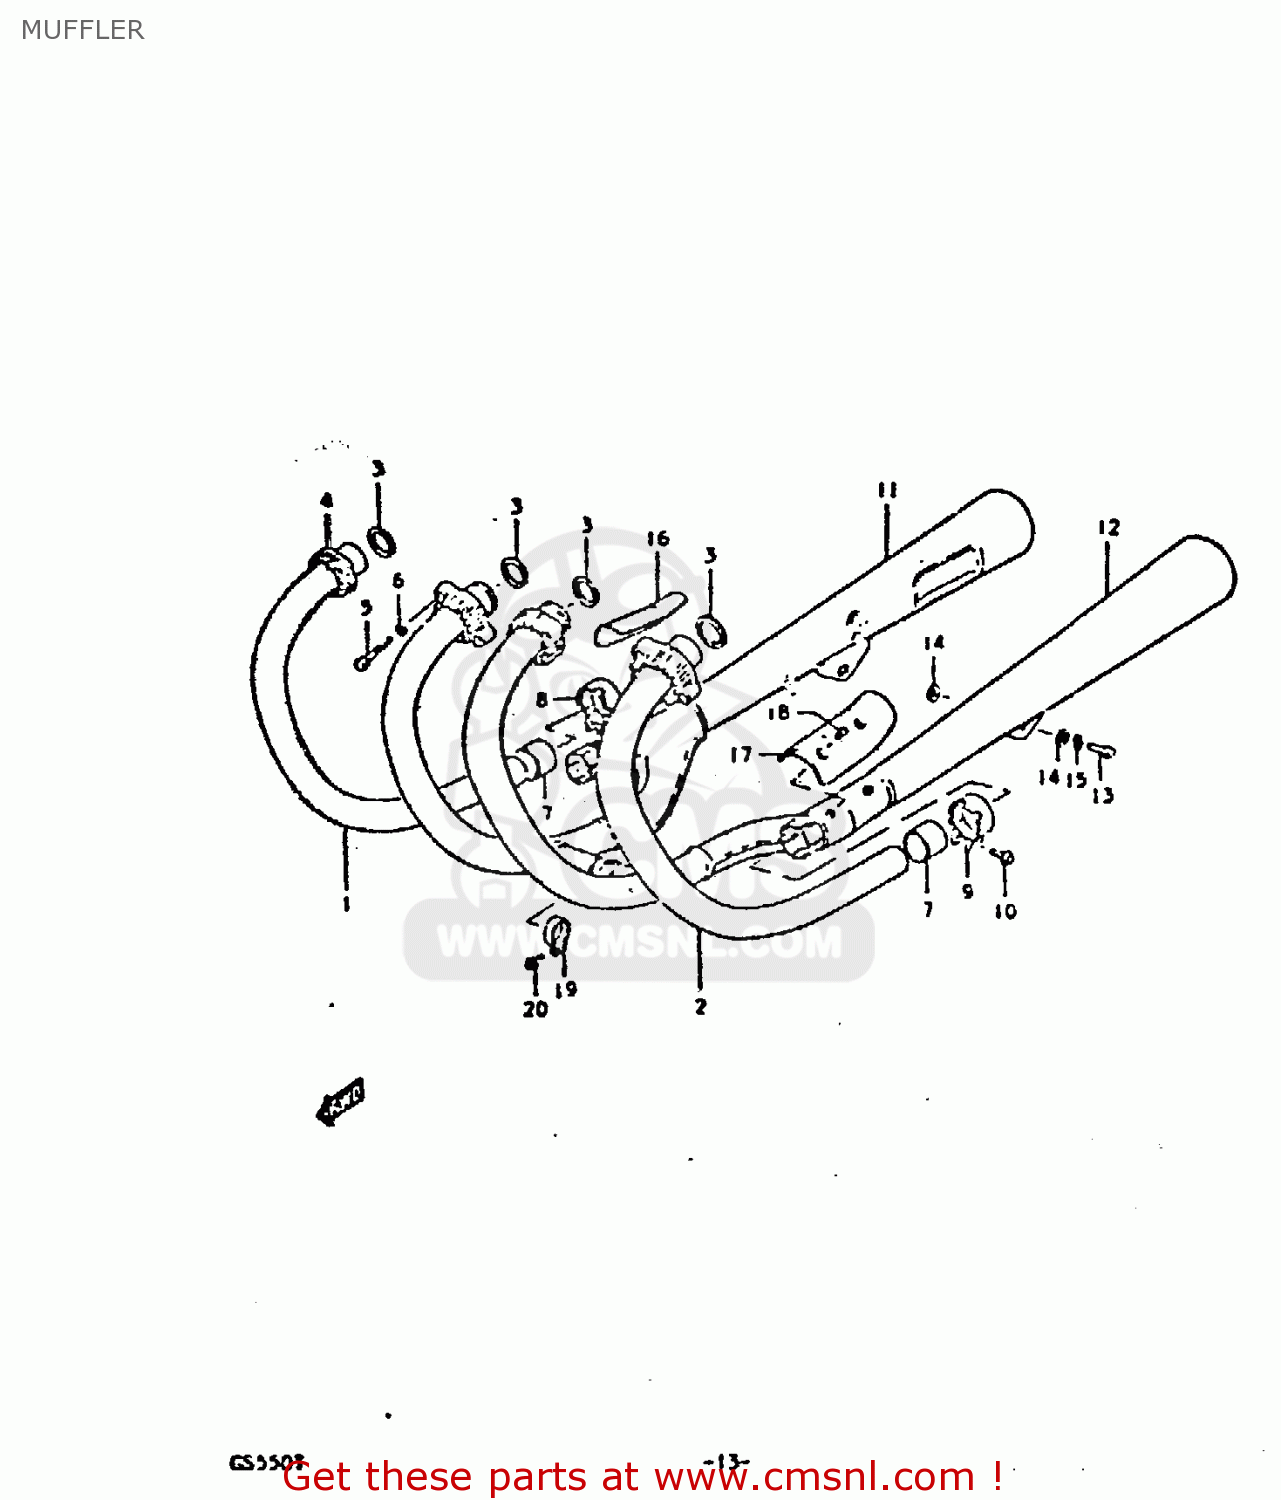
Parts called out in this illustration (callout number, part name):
1	PIPE,EXHAUST,RIGHT
2	PIPE,EXHAUST,LEFT
3	GASKET,EXHAUST PIPE (NAS)
4	CLAMP,EXHAUST PIPE
5	BOLT
6	LOCK WASHER
7	CONNECTOR,MUFFLER
8	CLAMP,MUFFLER CONNECTOR,R
9	CLAMP,MUFFLER CONNECTOR,L
10	BOLT
11	BODY,MUFFLER
12	BODY,MUFFLER
13	BOLT 10X30
14	WASHER
15	LOCK WASHER
16	COVER,MUFFLER,RIGHT
17	COVER,MUFFLER,LEFT
18	SCREW
19	CLAMP,EXHAUST COUPLER
20	BOLT,REAR
